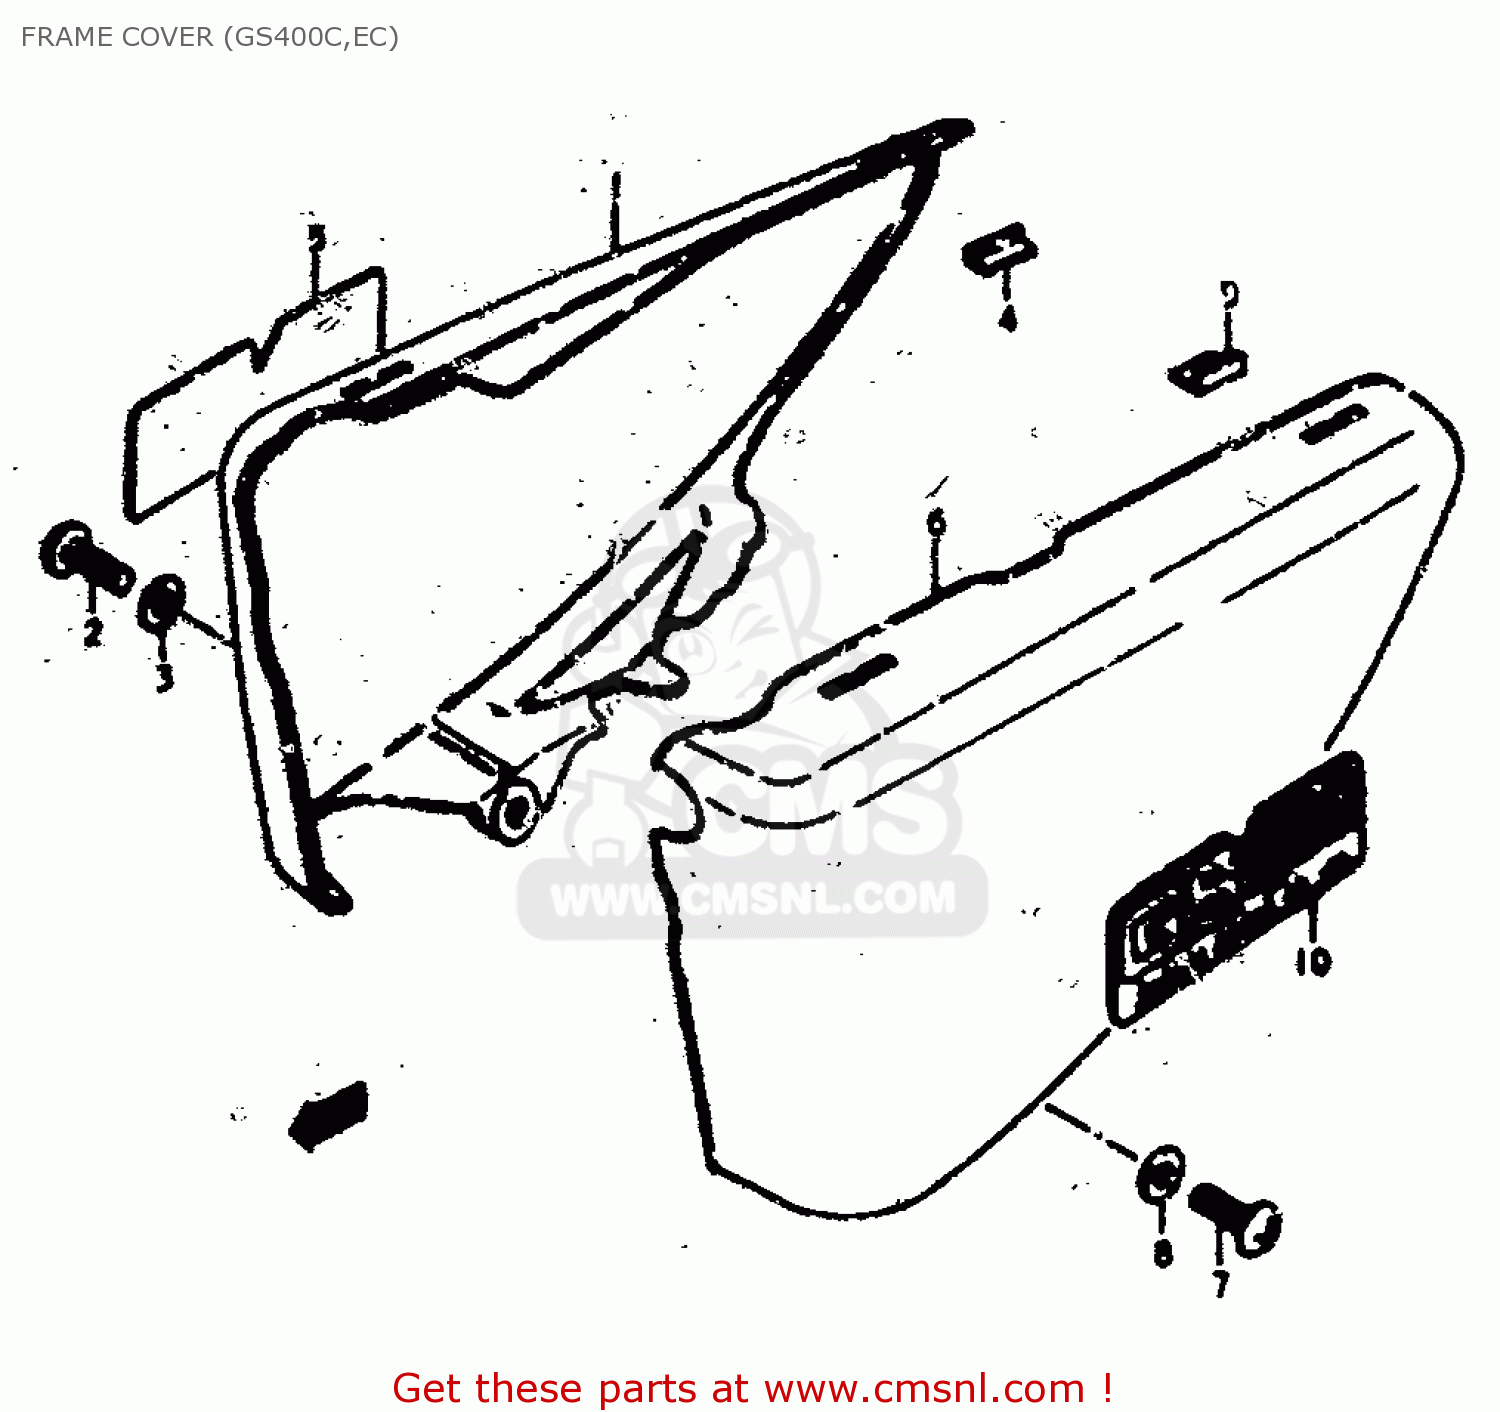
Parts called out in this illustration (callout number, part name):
1	COVER,FRAME,RIGHT
2	SCREW (6X15)
3	WASHER (6.5X18X1.6)
4	CUSHION,FRAME COVER
5	EMBLEM
6	COVER,FRAME,LEFT
7	SCREW
8	WASHER (6.5X18X1.6)
9	CUSHION,FRAME COVER
10	EMBLEM
